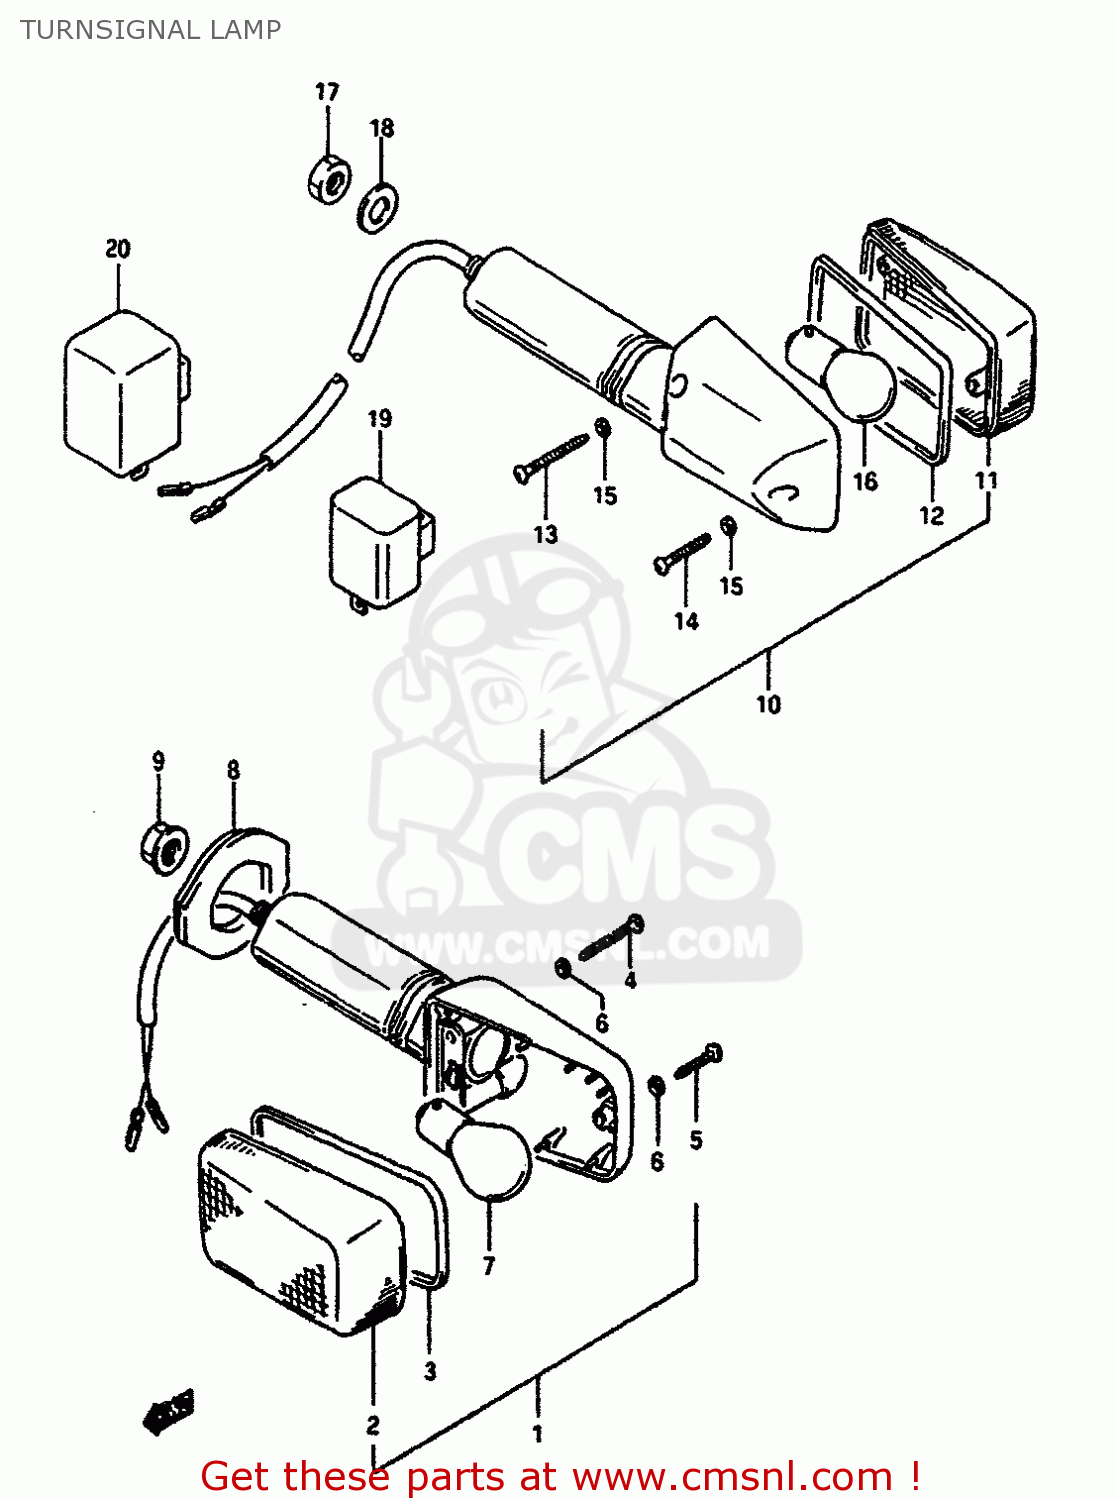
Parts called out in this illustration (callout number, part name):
1	LAMP ASSEMBLY,FRONT TURN SIGNAL
2	LENS
3	GASKET (NAS)
4	SCREW(3X30)
5	SCREW
6	GASKET (NAS)
7	BULB(12V21W)
8	GROMMET
9	NUT
10	LAMP ASSEMBLY,REAR TURN SIGNAL
11	LENS
12	GASKET (NAS)
13	SCREW(3X30)
14	SCREW
15	GASKET (NAS)
16	BULB(12V21W)
17	NUT
18	WASHER 10MM
19	RELAY ASSEMBLY,TURN SIGNAL
20	RELAY ASSY,TUR
